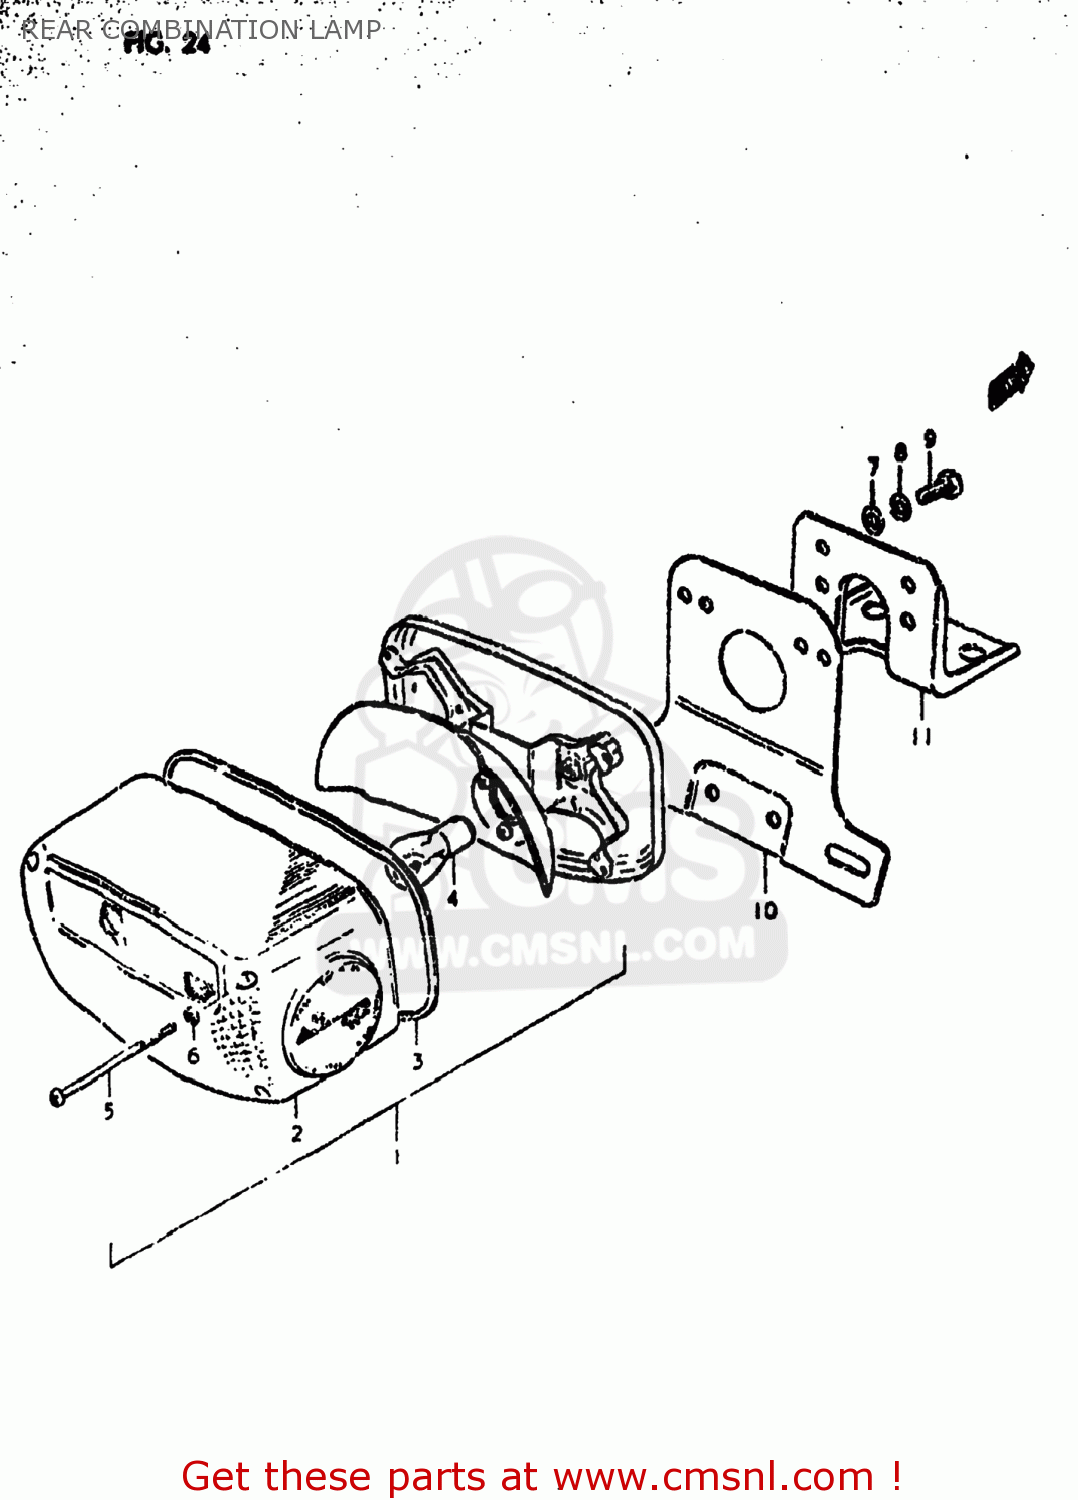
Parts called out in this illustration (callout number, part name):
1	LAMP ASSEMBLY,REAR COMBINATION
2	LENS,REAR COMBINATION LAMP
3	GASKET (NAS)
4	BULB(12V23W)
5	SCREW (4X55)
6	GASKET (NAS)
7	WASHER
8	LOCK WASHER
9	BOLT
10	BRACKET,LICENSE PLATE
11	BRACKET,LICENSE PLATE
